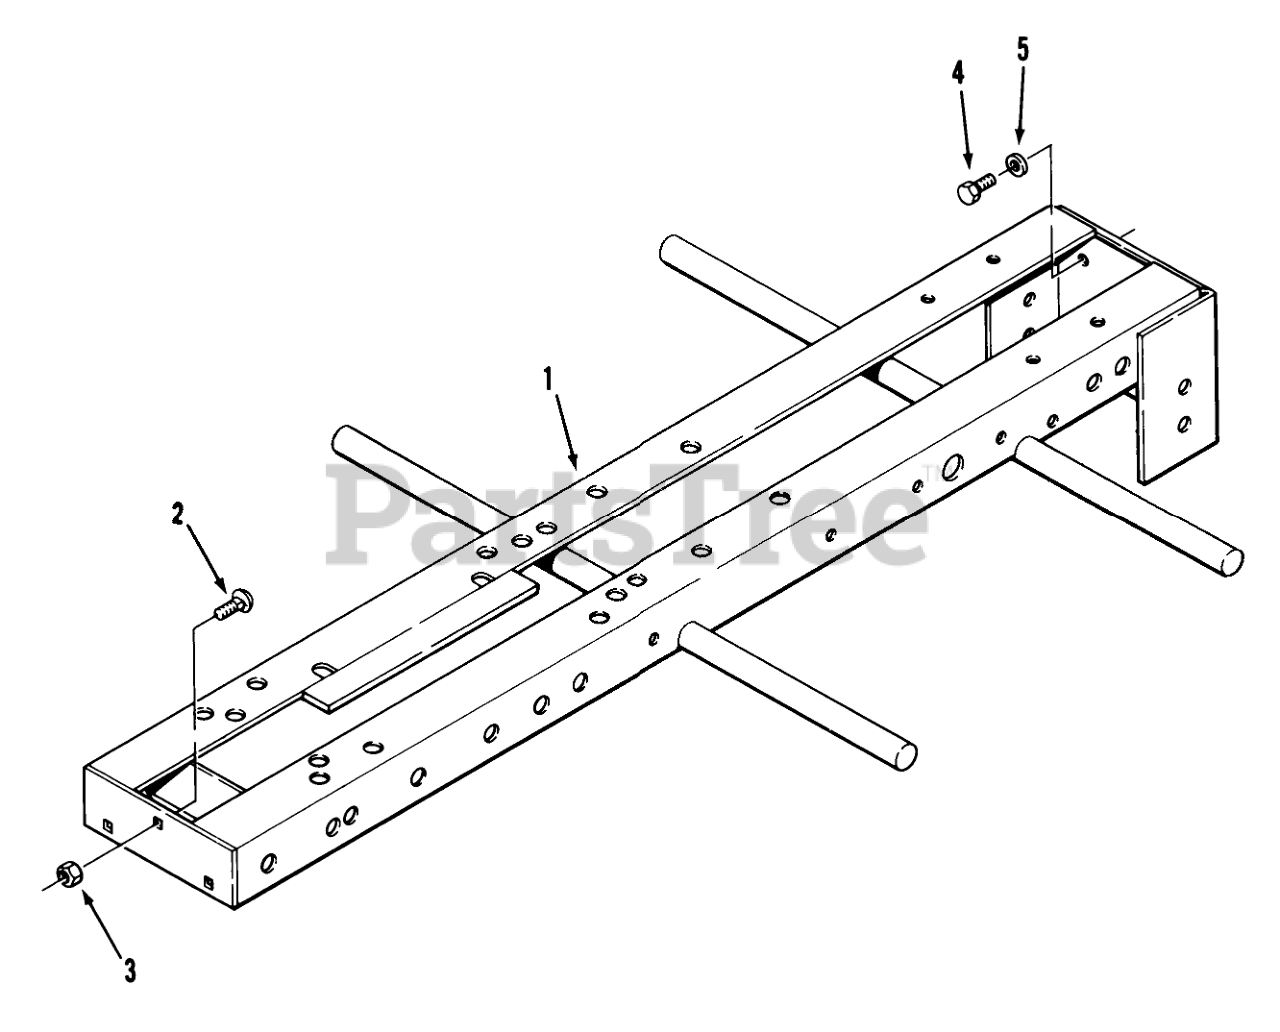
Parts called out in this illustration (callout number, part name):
1	Frame-01-19KE01 Only
1	Frame (Illustrated)-01-19KE02 Only
2	Bolt
3	Nut
4	Bolt 3/8-16 x 1 Grade 8
5	LOCKWASHER
